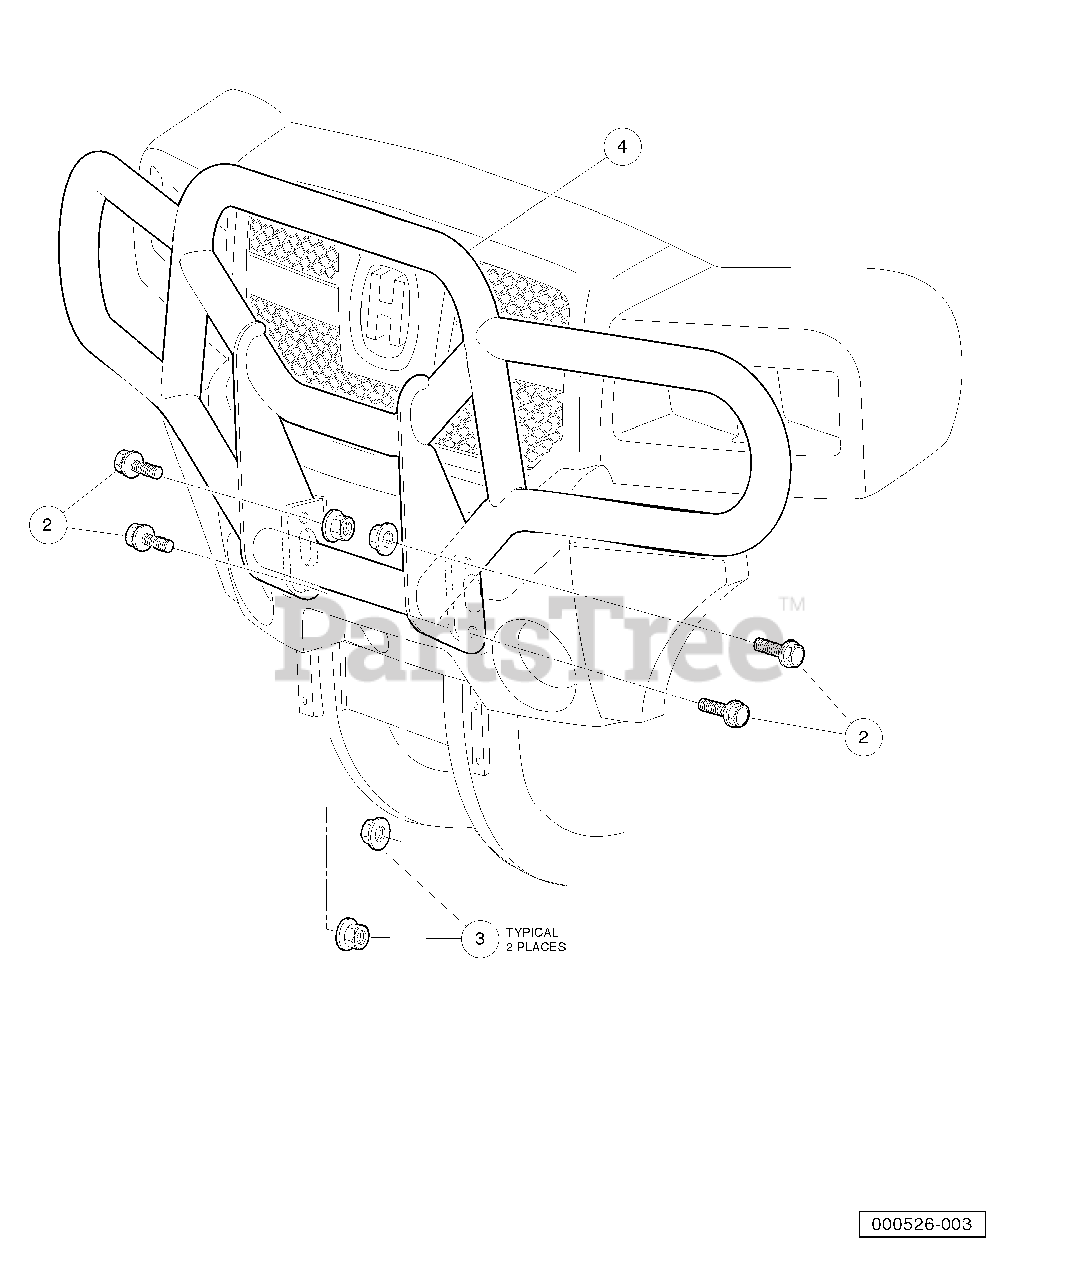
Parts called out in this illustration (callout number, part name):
1	Kit, Brush Guard Hus
2	Screw, M10 X 1.25 X 30 Hex Blk
3	Nut, Flg, M10 X 1.25 Hex Blk
4	Weldment, Brushguard, HUV 4421
